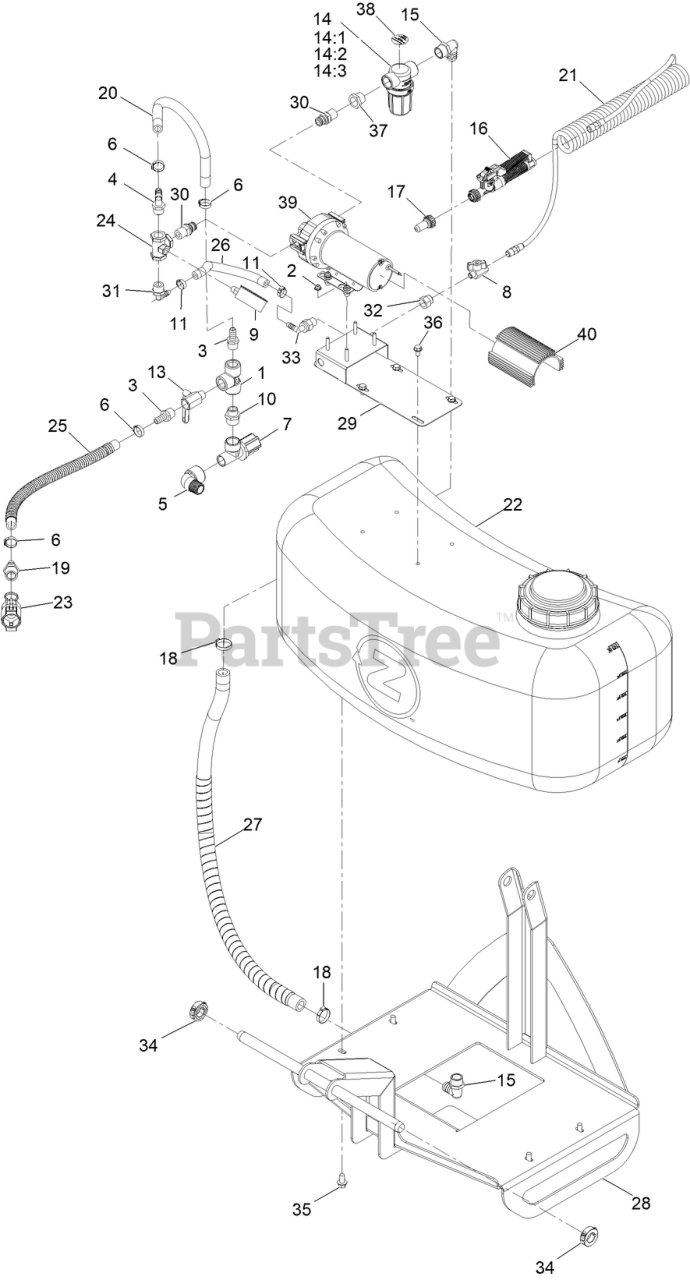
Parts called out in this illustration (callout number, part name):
3	FITTING-HOSEBARB
4	FITTING-ELBOW, HOSEBARB
5	ELBOW-90DEG
6	CLAMP-OETIKER, 167
7	VALVE-THROTTLE
8	VALVE-CHROME, 1/4
9	GAUGE
10	FITTING-NIPPLE
11	CLAMP-OETIKER, 167
13	VALVE-CHROME, 1/2
14	STRAINER-INLINE
14:1	BOWL-STRAINER
14:2	GASKET-HEAD, LINE STRAINE
14:3	Screen-Strainer, 50 Mesh
15	FITTING-ELBOW, 90
16	GUN-SPRAY, SPOT
17	TIP-SPRAY, #12 SPOT
18	Clamp-Oetiker, 167
19	FITTING-STRAIGHT
20	HOSE-SPRAY
21	HOSE-COILED, 15 FT
22	ASM-TANK, 30 GAL
23	COUPLER-FEMALE
24	FITTING-CROSS
25	Hose-Spray, Wrapped
26	Hose-Spray
27	Hose-Spray, Wrapped
28	BASE-30 GAL ATTACH
29	PUMP MOUNT, 30 GALLON ATT
30	PUMP FTG X 1/2MPT FQ5MS-1
31	FITTING-ELBOW-90
32	OUTLET ADAPTER\N3NF1614
33	BOOM ELBOWS\N3NTL38
34	Collar-Shaft, Split, Cz
35	Screw-HH Flg 3/8-16 X 3/4
36	SCREW-HHF
37	REDUCER-BUSHING, PLASTIC
38	DECAL-CAP, STRAINER
39	PUMP-5.3 GPM
40	HEATSINK-3.0""
